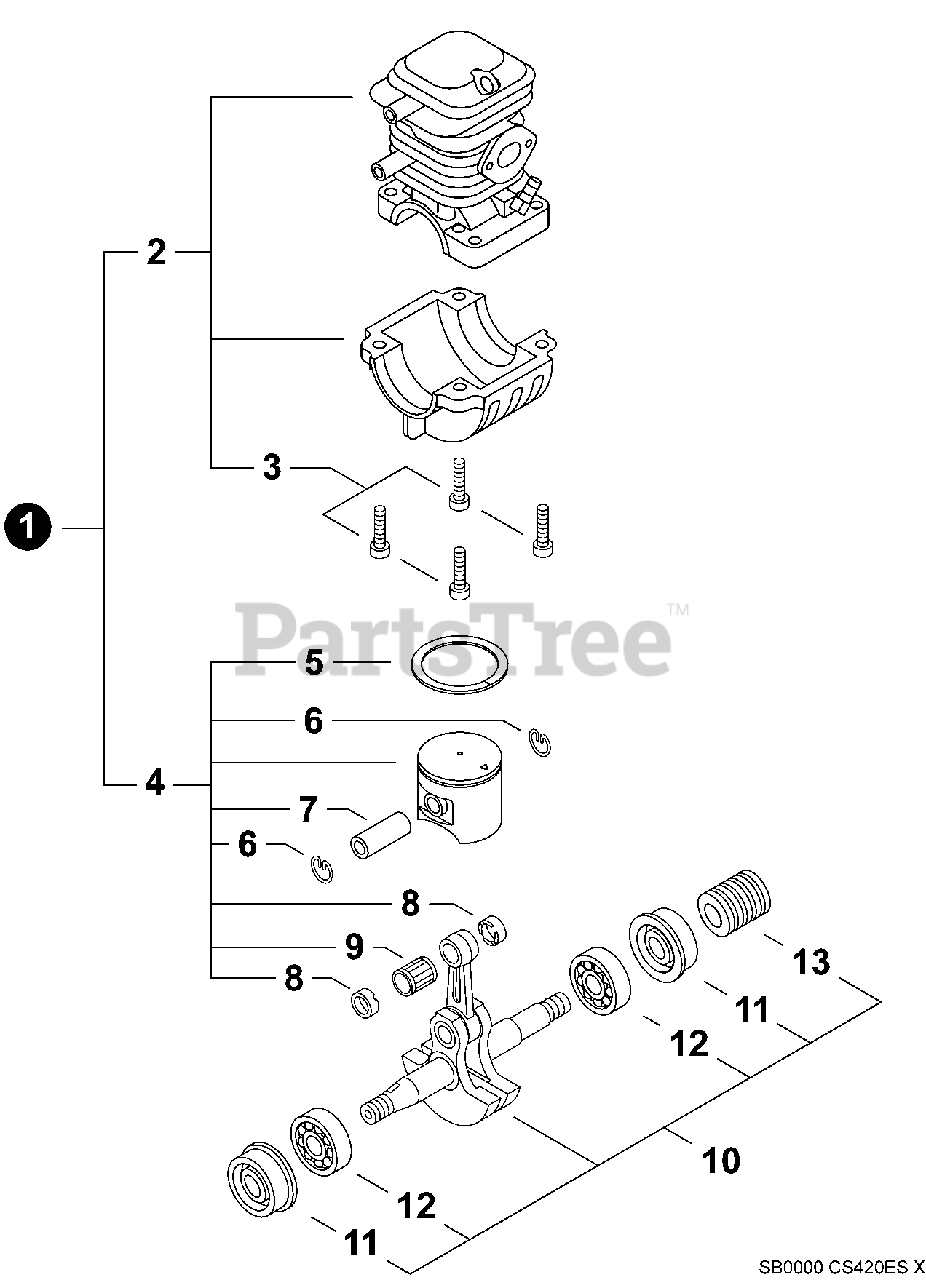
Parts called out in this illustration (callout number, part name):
1	REPAIR KIT, ENGINE
2	CRANKCASE KIT
3	BOLT 5×22
4	PISTON KIT
5	RING, PISTON
6	RING, SNAP
7	PIN, PISTON
8	WASHER, THRUST
9	BEARING, NEEDLE 9
10	CRANKSHAFT ASSY
11	SEAL, OIL 12
12	BEARING, BALL - 6201 C3
13	GEAR, WORM
